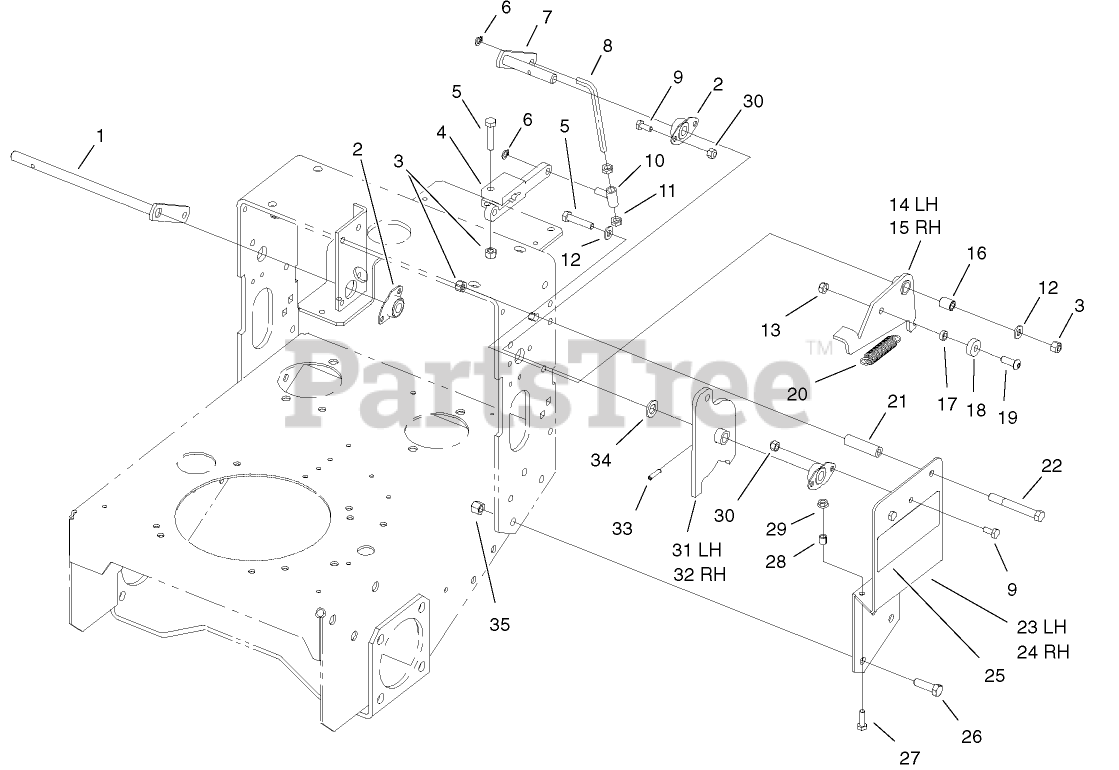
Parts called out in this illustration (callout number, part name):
1	LEVER-PIVOT, RH
2	SIDE FLANGE BEARING ASM
3	NUT-LOCK, NI
4	ARM-PUMP
5	SCREW-HH
6	RING-GRIP
7	LEVER-PIVOT, LH
8	ROD-LINK
9	SCREW-HH
10	SLEEVE
11	NUT-JAM
12	WASHER-PLAIN
13	NUT-LOCK, NI
14	ARM-DETENT, LH
16	BUSHING-ARM, DETENT
17	SPACER-BEARING
18	BEARING-BALL
19	SCREW-HSBH
20	SPRING-DETENT
21	STOP-REVERSE
22	SCREW-HH
23	BRACKET-PIVOT, LEFT
25	DECAL-HYDRO
26	SCREW-HH
27	SCREW-HH
28	SPACER-TUBULAR
29	NUT-LOCK, HHF
30	NUT-LOCK, NI
31	ARM-PIVOT, LH
33	PIN-ROLL, SLOTTED
34	WASHER-THRUST
35	NUT-LOCK, NI
